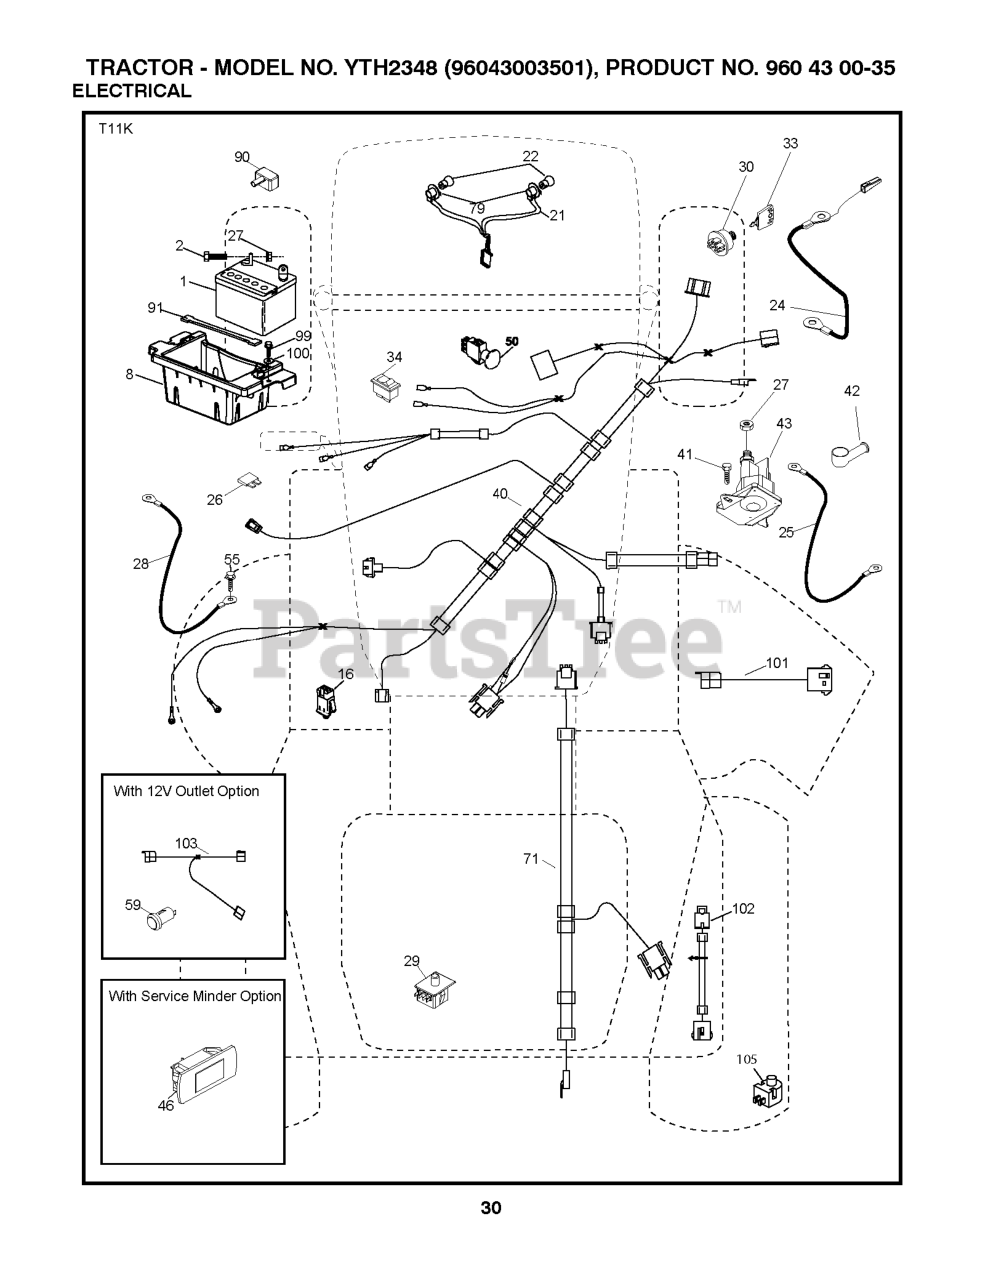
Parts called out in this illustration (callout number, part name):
1	Battery 12 Volt 25 Amp
2	BOLT.HEX.1/4.X.3/4.DICHROMATE
8	BOX.BATTERY.MOUNT.FRONT.LT
16	SWITCH INTERLOOK PUSH-IN
21	HARNESS ASSY LIGHT
24	CABLE.BATT.POS.WIRE.TG.DA SOL
25	CABLE.STARTER.6G.BL/RED.17.5
26	FUSE 20AMP
27	NUT
28	CABLE GROUND 6 GA 21" 90T BLK
29	SWITCH.SEAT.DELTA.OPC.
30	SWITCH.IGN.DELTA.W.LGH.ROS
33	KEY.CHAIN.BLISTER.PACK.GEN.INT
40	HARNESS.IGN.DASH.HUQ/P
41	SCREW
42	TERMINAL COVER
43	SOLENOID.W/BRASS.PLUNGER
46	RP.GUAGE.SRVCMNDR.HRMTR.
50	RP.PTO.SWITCH.8 TERMINAL.BLACK
55	SCREW 5/16"
71	HARNESS-CHASSIS SUB
79	BULB HOLDER ASM.
90	COVER.TERMINAL.BATTERY
91	STRAP.BATTERY.MOUNT.FRONT(2 2)
99	SCREW HEXWSHR 1/4-20X3/4
101	PIGTAIL.MATNLK.NEW.HAR
102	HARNESS PIGTAIL PCH TEX ROS
105	REVERSE SWITCH
